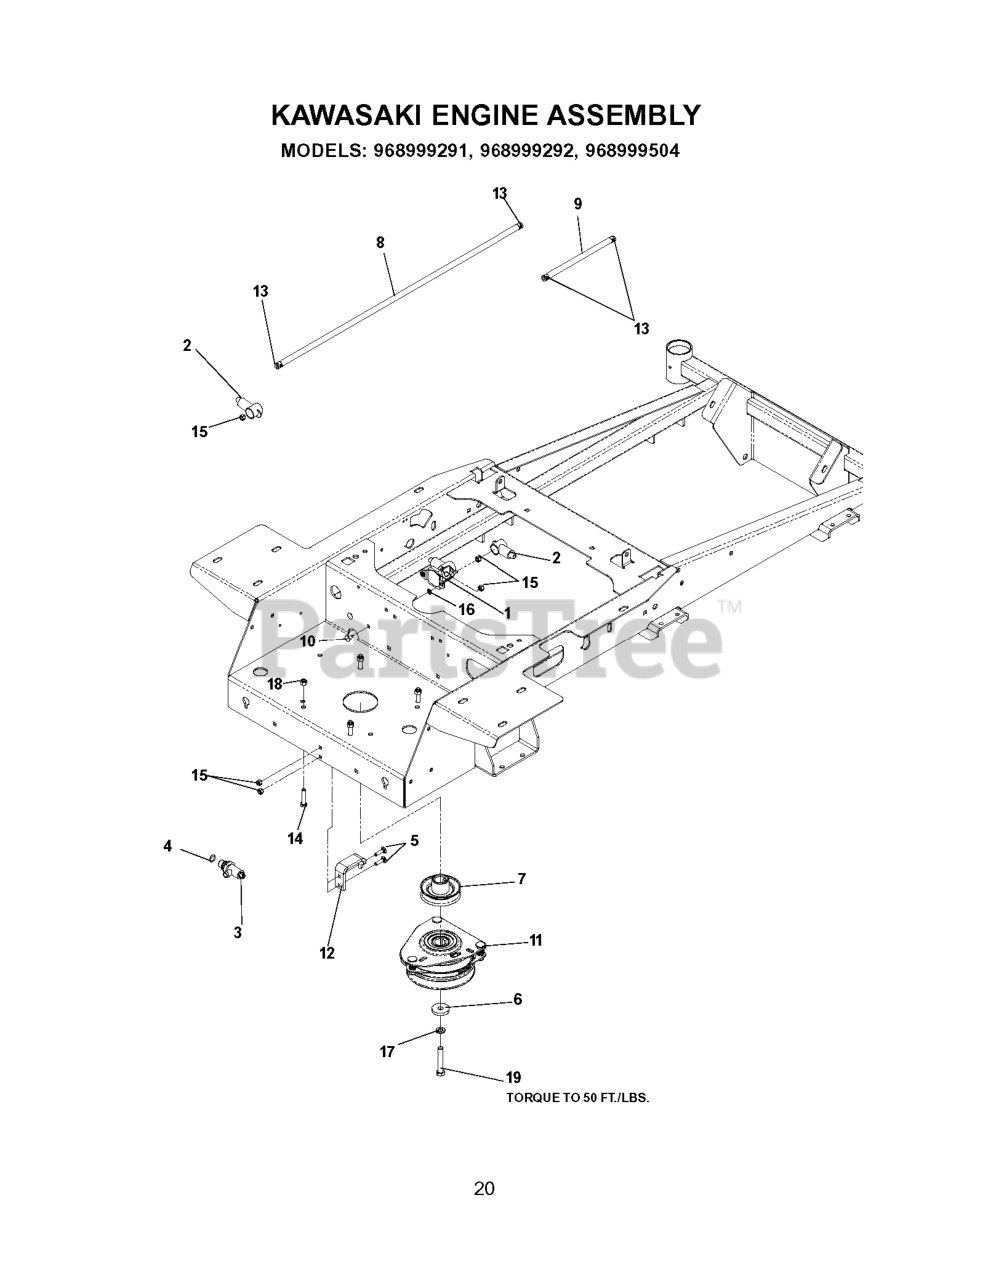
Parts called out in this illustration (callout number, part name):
3	VALVE ASSEMBLY
5	RHSNB, 1/4-20 X 1, GR5
6	CLUTCH, WASHER
8	FUEL LINE 24"
9	FUEL LINE 5"
10	RHSSNB, 1/4-20X5/8
12	CLUTCH TIE DOWN
13	HOSE CLAMP
14	CAPSCREW 5/16 X 1/1/2 HEX HEAD
15	NUT.1/4-20.HEX.NYLOC.ZD
16	WASHER 1/4 INT TOOTH
17	WASHER 7/16 LOCK
18	NUT 5/16 NYLOC
19	BOLT 7/16F X 2 1/2
